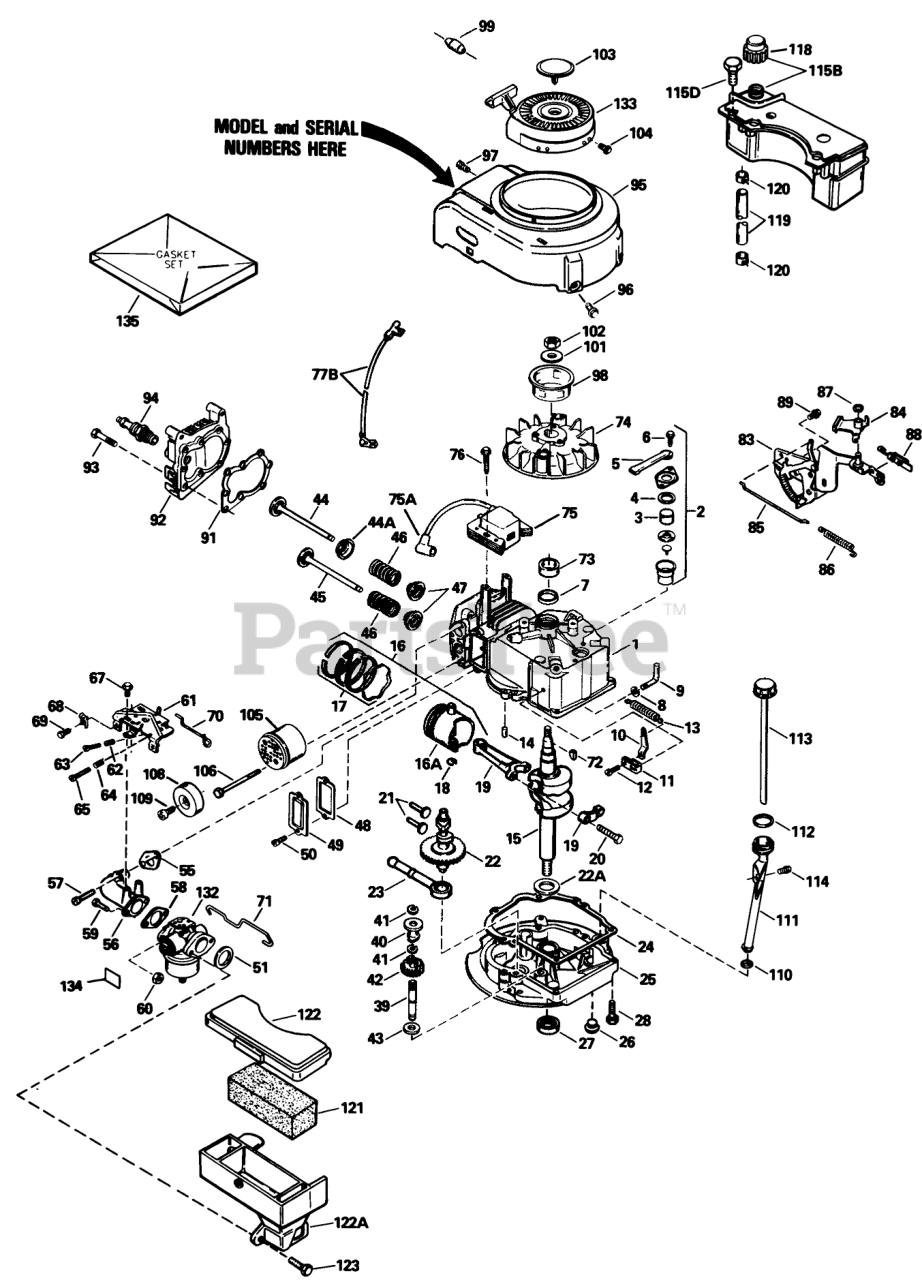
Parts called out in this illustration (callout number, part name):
1	Cylinder Assembly (Incl. Ref. #7 & 14)
2	Breather Assembly (Incl. Ref. #3-6)
3	Element-Breather
4	Gasket-Breather
5	Tube, Breaker
6	Screw (10-24 x 9/16)
7	Seal-Oil
8	Washer-Flat
9	Rod-Governor (Incl. Ref. #8)
10	Governor Lever
11	Clamp-Lever, Governor
12	Screw
13	Spring Governor
14	Pin-Dowel
15	Crankshaft
16	Piston-Pin & Ring Assy. (Std.)(Incl. Ref. #16A, 17 & 18)
16	Piston-Pin & Ring Assembly (.010 oversize)(Incl. Ref. #16A, 17 & 18)
16	Piston-Pin & Ring Assembly (.020 oversize)(Incl. Ref. #16A, 17 & 18)
16A	Piston & Pin Assembly (Std.)(Incl. Ref. #18)
16A	Piston & Pin Assembly (.010 oversize) (Incl. Ref. #18)
16A	Piston & Pin Assembly (.020 oversize) (Incl. Ref. #18)
17	Ring Set-Piston (Std.)
17	Ring Set, Piston(.0100versize)
17	Ring Set (.020" OS)
18	Ring-Retaining, Piston Pin
19	Rod Assembly-Connecting (Incl. Ref. #20)
20	Bolt-Rod, Connecting
21	Lifter-Valve
22	Camshaft(Mech.Comp. Release)
22A	Washer-Thrust
23	Oil Pump ASM
24	Gasket
25	Flange-Mounting (Incl. Ref. #26, 27 & 39)
26	Plug Oil Drain
27	Seal-Oil
28	Screw (1/4-20 x 1-1/4)
39	Shaft-Governor
40	Spool-Governor
41	Ring-Retaining
42	Gear Assembly-Governor (Incl. Ref. #43)
43	Washer
44	Valve-Intake (Std.)(Incl. Ref. #47)
44	Valve-Intake (1 /32" oversize)(Incl. Ref. #47)
44A	Seal Assy., Intake
45	Valve-Exhaust (Std.)(Incl. Ref. #47)
45	Valve-Exhaust (1 /32" oversize) (Incl. Ref. #47)
46	Spring-Valve
47	Cap-Valve, Spring
48	Gasket-Cover, Valve
49	Cover-Valve
51	Gasket-Cleaner, Air
55	Gasket-Intake Pipe
56	Pipe-Intake (Incl. Ref. #55)
57	Screw (1/4-20 x 1)
59	Screw (1/4-28 x 7/8)
60	Nut and Lock Washer (1/4-28)
61	Bracket Assembly-Control (Incl. Ref. #62-65)
62	61709/GIL1515A/95-5
63	Screw
64	Spring-Compression
65	Screw
67	Screw (10-24 x 9/16)
68	Conduit
69	Screw (10-32 x 3/8)
70	2035A67 ADD.ASSEMBL
71	Link-Throttle
72	Key-Flywheel
74	Flywheel
75	Solid State
75A	Cover-Spark Plug
76	Screw
77B	Ground Wire
83	Bracket-S.E. Brake
84	Lever-Brake
85	Link-Control
86	Spring-Extension
87	Ring-Retaining
88	Terminal
89	Screw (1/4-20 x 3/8)
91	Gasket-Cylinder Head
92	Head-Cylinder
93	Screw (5/16-18x1-1/2)
94	Spark Plug-Resistor (R J19 L M)
95	Housing-Blower
96	Screw (1/4-20 x 1/2)
97	Screw (10-24 x 9/16)
98	Hub-Starter
99	Retainer-Starter Rope
101	Washer-Belleville
102	Nut-Flywheel
103	Plug Starter
104	Screw, Hex Hd.
105	Muffler Assembly (Incl. Ref. #106)
108	Cover-Muffler
109	Screw (8-32 x 3/8)
111	Oil Fill Tube
113	Dipstick
114	Screw (10-32 x 1/2)
115B	Tank Assembly (Incl. Ref. #118 & 126)
115D	Screw (10-32 x 35/64)
118	Cap-Fuel
119	Line-Fuel
120	Clamp-Line, Fuel
121	Filter-Air Cleaner
122	Cover Air Cleaner
122A	Body Air cleaner
132	Carburetor (Incl. Ref. #58)
133	Starter-Rewind
134	Decal-Primer
135	Gasket Set (Incl. Items Marked )
